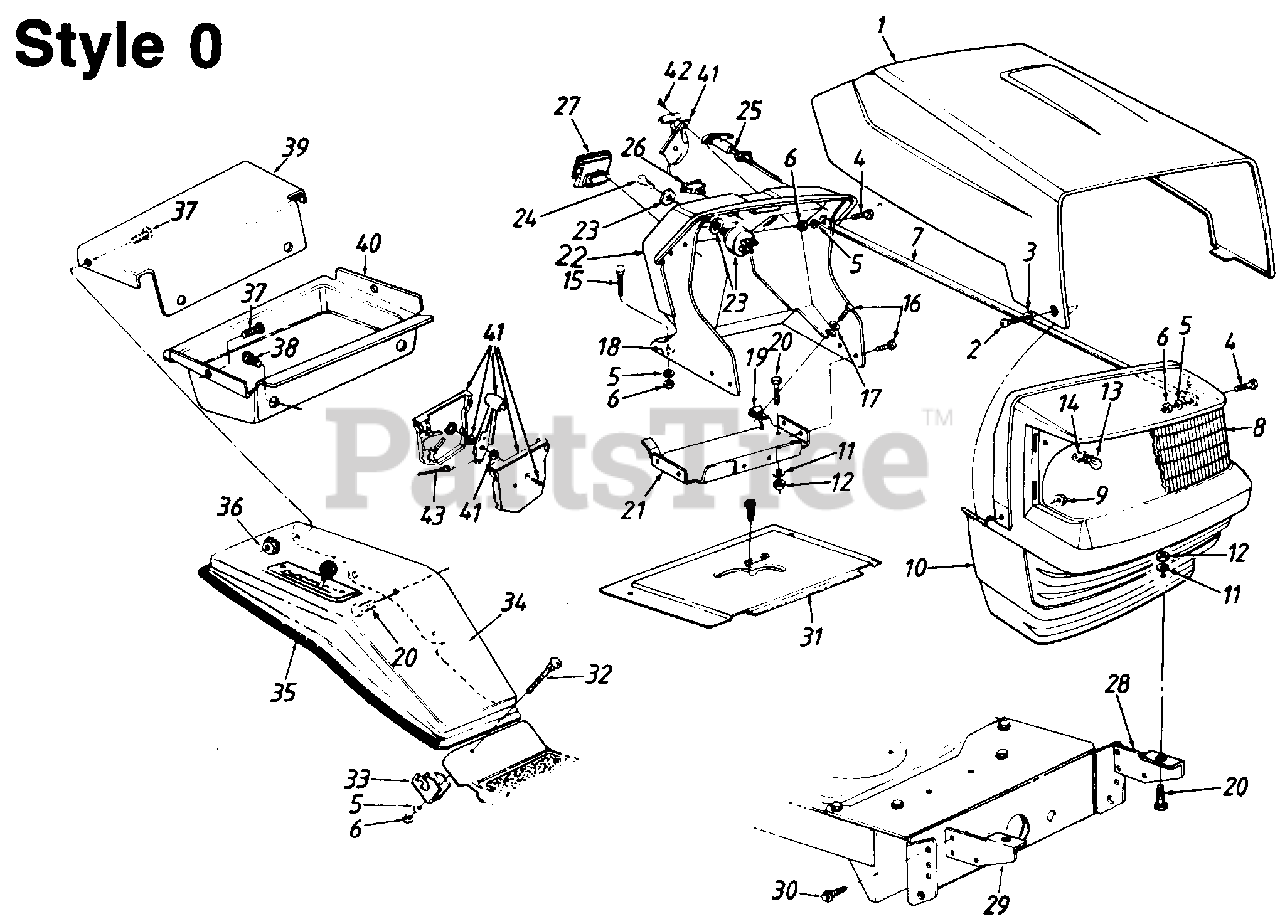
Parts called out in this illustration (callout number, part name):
1	Hood
2	Shld. Bolt .375" Dia. x .125" Lg.
3	Spr. Wash. .265" I.D. x .562" O.D.
4	Hex Bolt 1/4-20 x .62" Lg.
5	L-Wash. 1/4" I.D.
6	Hex Nut 1/4-20 Thd.
8	Headlight Lens
9	Flange L-Nut 1/4-28 Thd.
10	Grille
11	L-Wash. 5/16" I.D.
12	Hex Nut 5/16-18 Thd.
13	Lamp
14	Socket
15	Carriage Bolt 1/4-20 x 1.0" Lg.
16	Hex Wash. Hd. TT-Tap Scr. 1/4-20 x .5" Lg.
17	Fl-Wash. .281" I.D. x .73" O.D.
18	Bolt Retainer 1/4" I.D.
19	Speed Nut 1/4-20 Thd.
20	Hex Bolt 5/16-18 x .75" Lg.
21	Gas Tank Support Brkt.
23	Ignition Switch
24	Ignition Key
25	Choke Control 20" Lg.
26	Light Switch
27	Ammeter
28	Grille Mtg. Brkt.-L.H.
31	Shift Cover
32	Carriage Bolt 1/4-20 x 2.0" Lg.
33	Fender Clamp
36	Hex Sems Nut #10-24 Thd.
37	Truss Mach. Scr. #10-24 x .5" Lg.
38	Hex Wash. Hd. AB-Tap Scr. 5/16 x .75" Lg.
41	Throttle Box Ass'y.
42	Truss Mach. AB-Tap Scr. #10 x .5" Lg.
43	Throttle Control Wire
